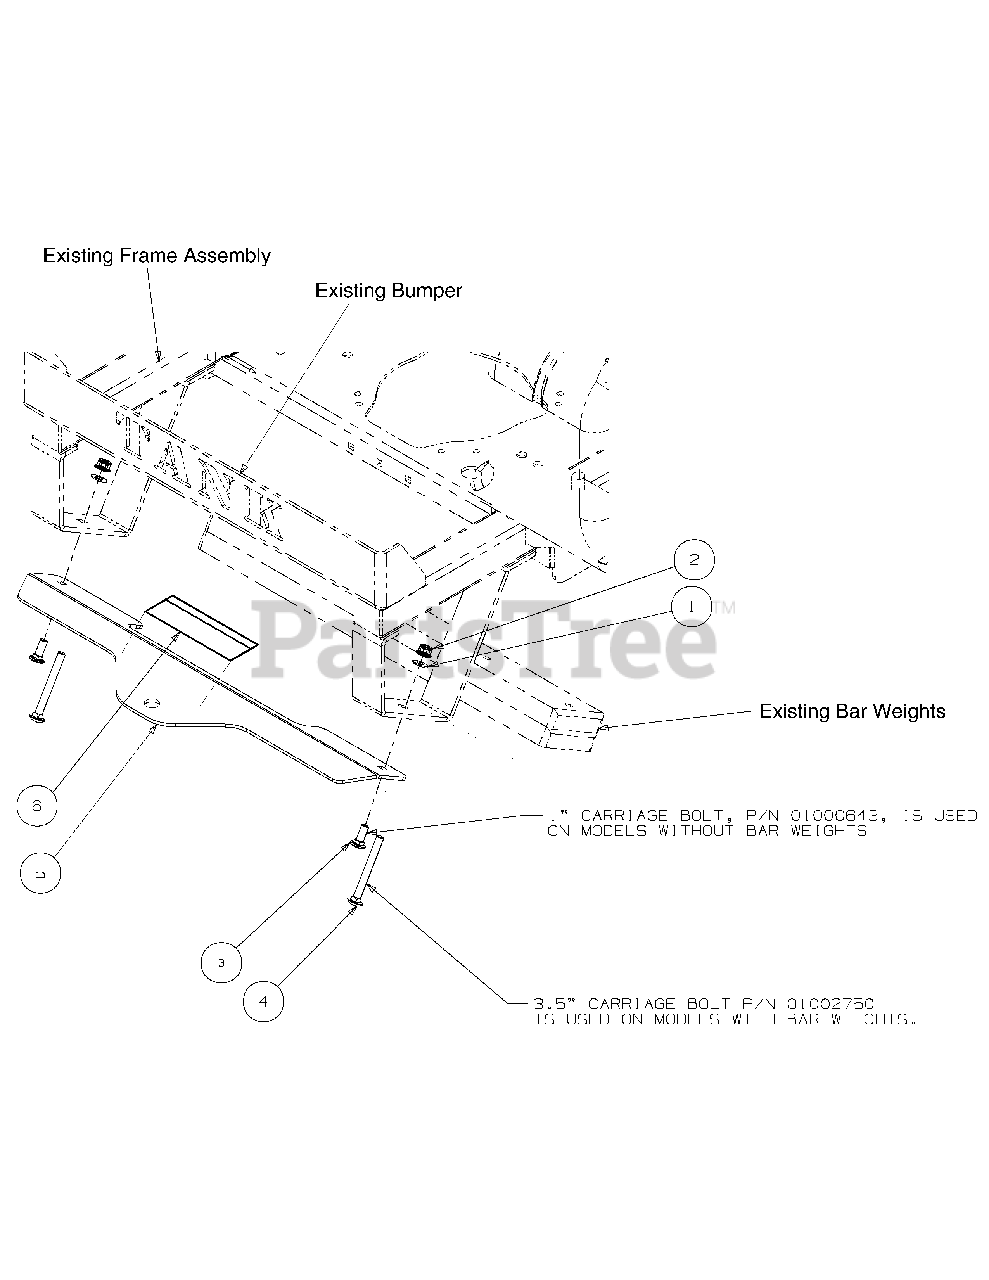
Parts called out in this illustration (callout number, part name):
1	Flat Washer, 3/8
2	Flange Lock Hex Nut, 3/8-16
3	Carriage Bolt, 3/8-16 x 1
4	Carriage Bolt, 3/8-16 x 3.5
5	Hitch
6	Decal, Hitch Warning
